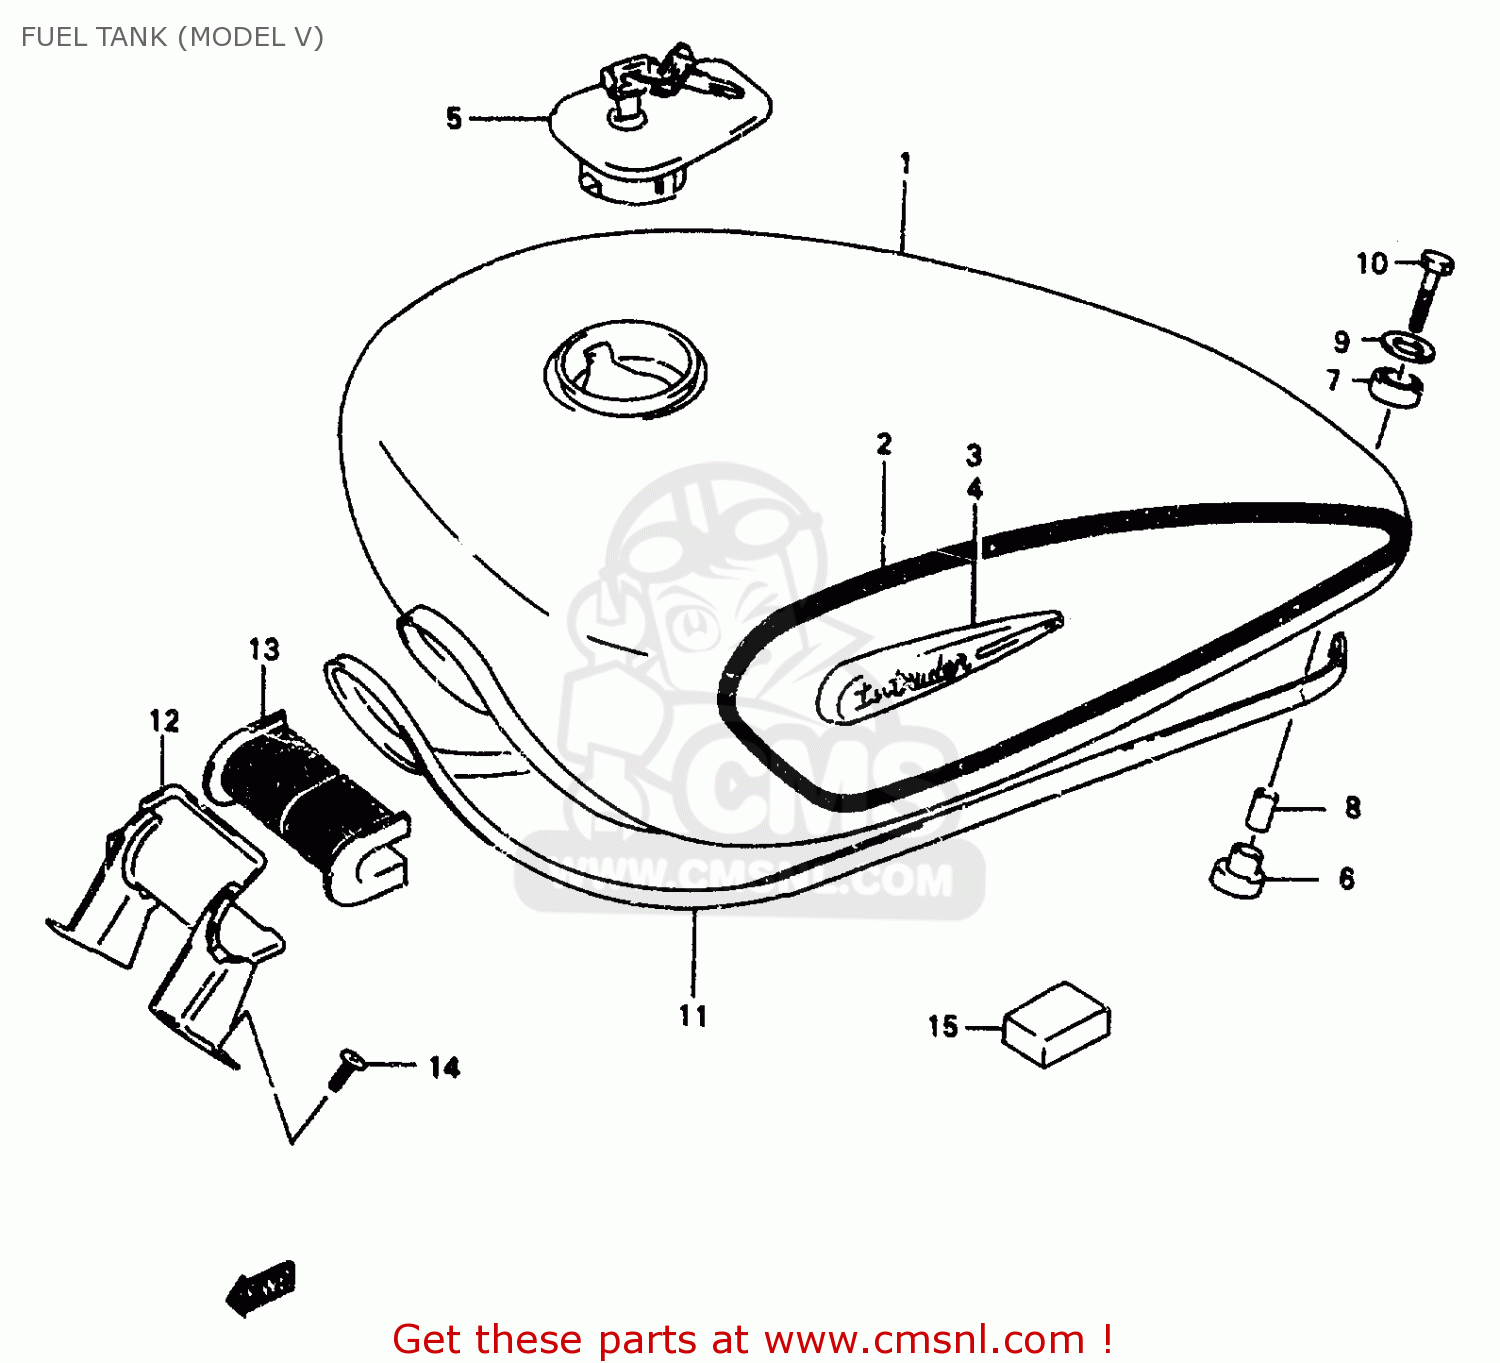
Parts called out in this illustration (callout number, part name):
1	TANK ASSY,FUEL
2	TAPE SET,FUEL TANK
3	EMBLEM,FUEL TANK,R
4	EMBLEM,FUEL TANK,L
5	CAP SET,FUEL TANK
6	CUSHION
7	CUSHION
8	SPACER(6.5X9X21.5)
9	WASHER (6.5X24X1.6)
10	SCREW
11	MOLDING
12	BRACKET COMP,FUEL TANK
13	CUSHION,FUEL TANK FR
14	SCREW
15	CUSHION
16	WASHER
17	CUSHION
